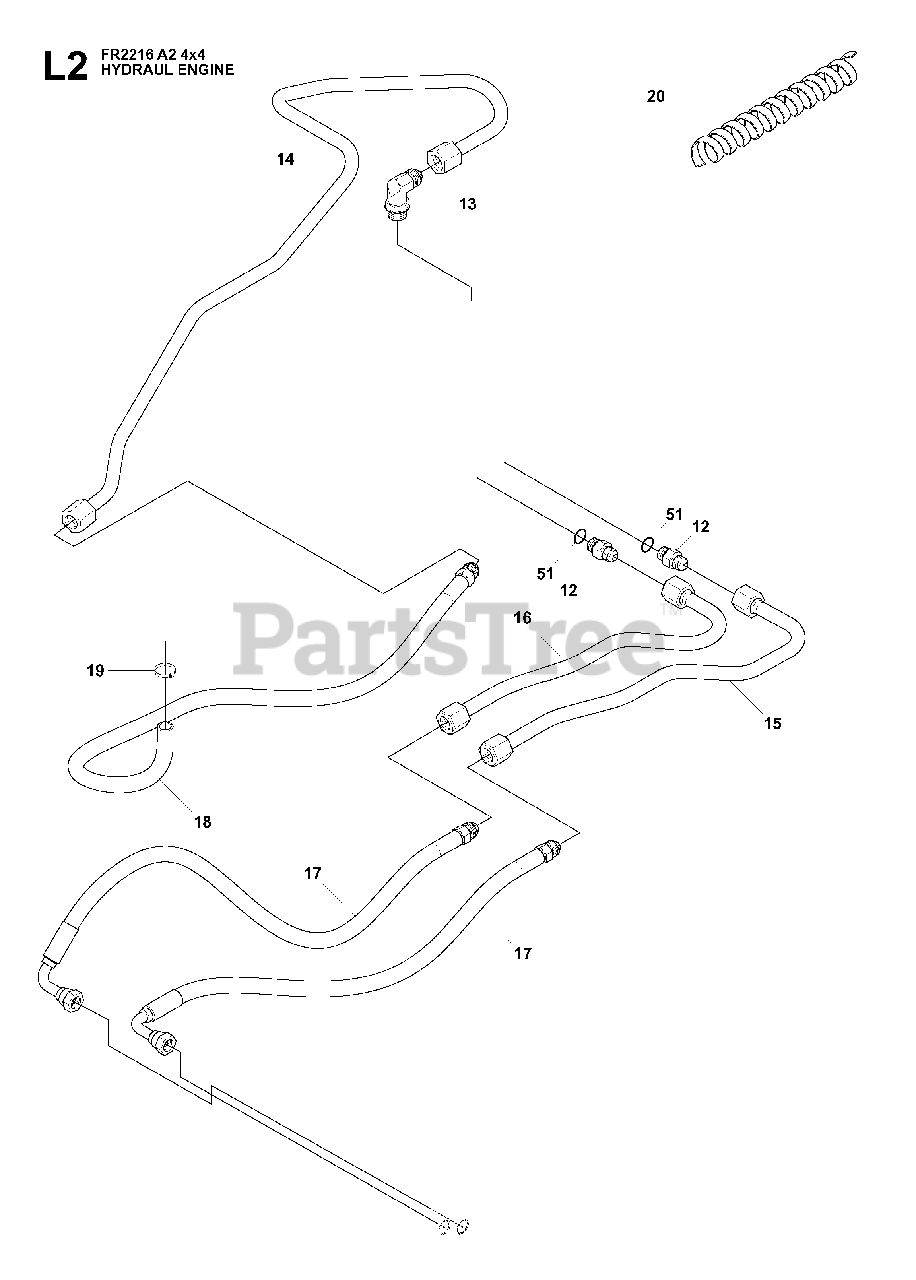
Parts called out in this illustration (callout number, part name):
12	PIPE FITTING
14	HYDRAULIC PIPE
15	HYDRAULIC PIPE
16	HYDRAULIC PIPE
17	HYDRAULIC HOSE
19	HOSE CLIP
20	PROTECTOR
